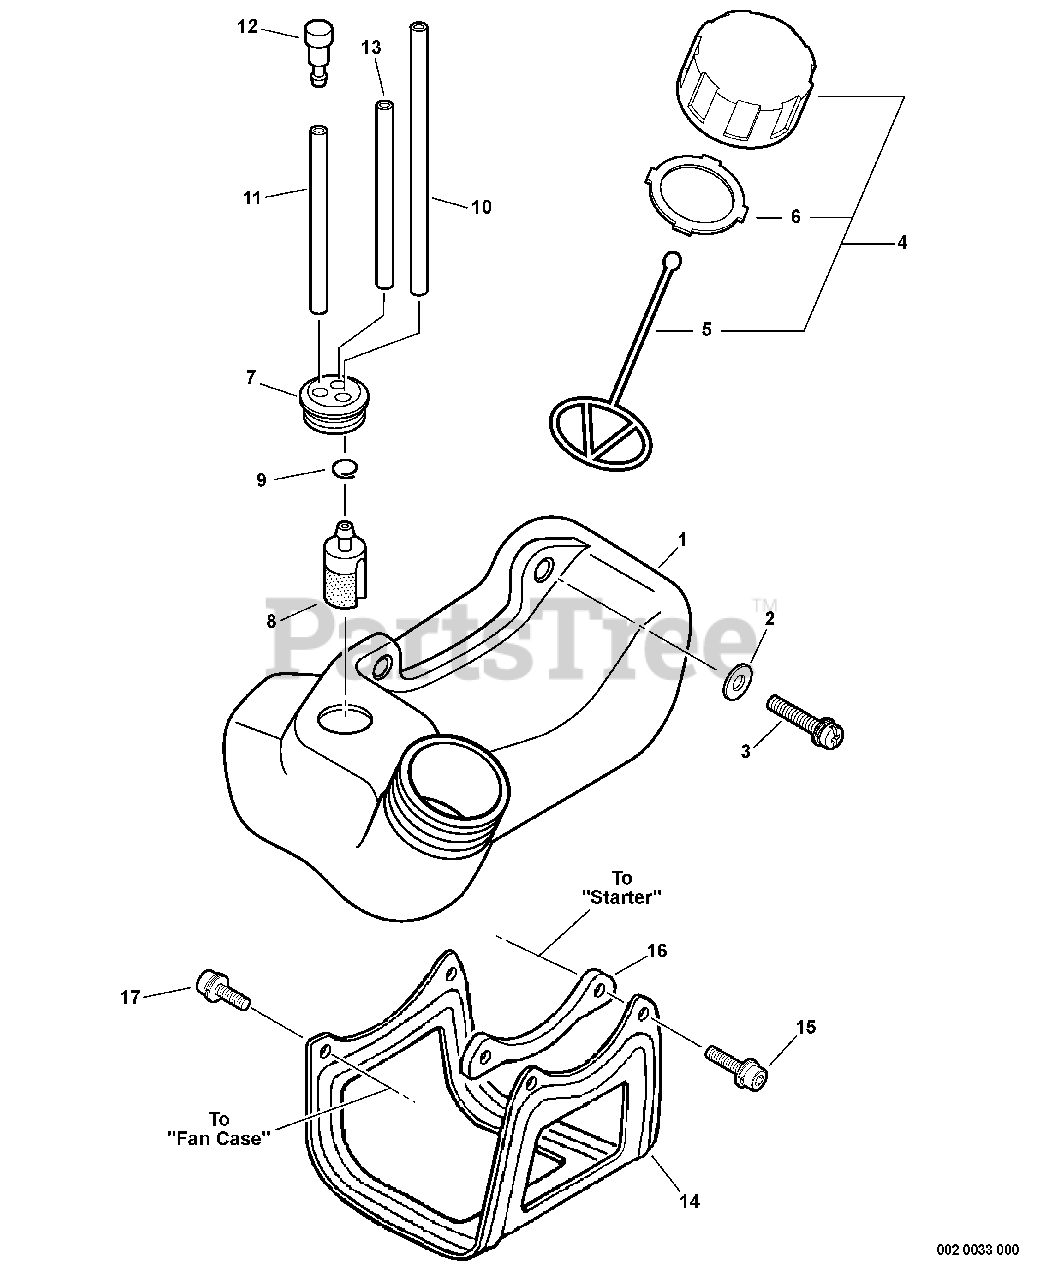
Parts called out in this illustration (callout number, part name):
1	TANK, FUEL
2	WASHER 5.5×12×0.8
3	SCREW 5×20
4	CAP ASSY, FUEL
5	CONNECTOR, CAP L= 100 MM
6	GASKET, FUEL CAP
7	GROMMET, FUEL
8	FILTER, FUEL
9	CLIP 6 MM
10	PIPE, FUEL 3x-5x-180
11	PIPE, FUEL 3x-5x-70 BLACK
12	VENT ASSY
13	PIPE, FUEL 3×6×80 CLEAR
14	GUARD, FUEL TANK
15	BOLT 4×20
16	PLATE, EYE
17	BOLT 4×16
